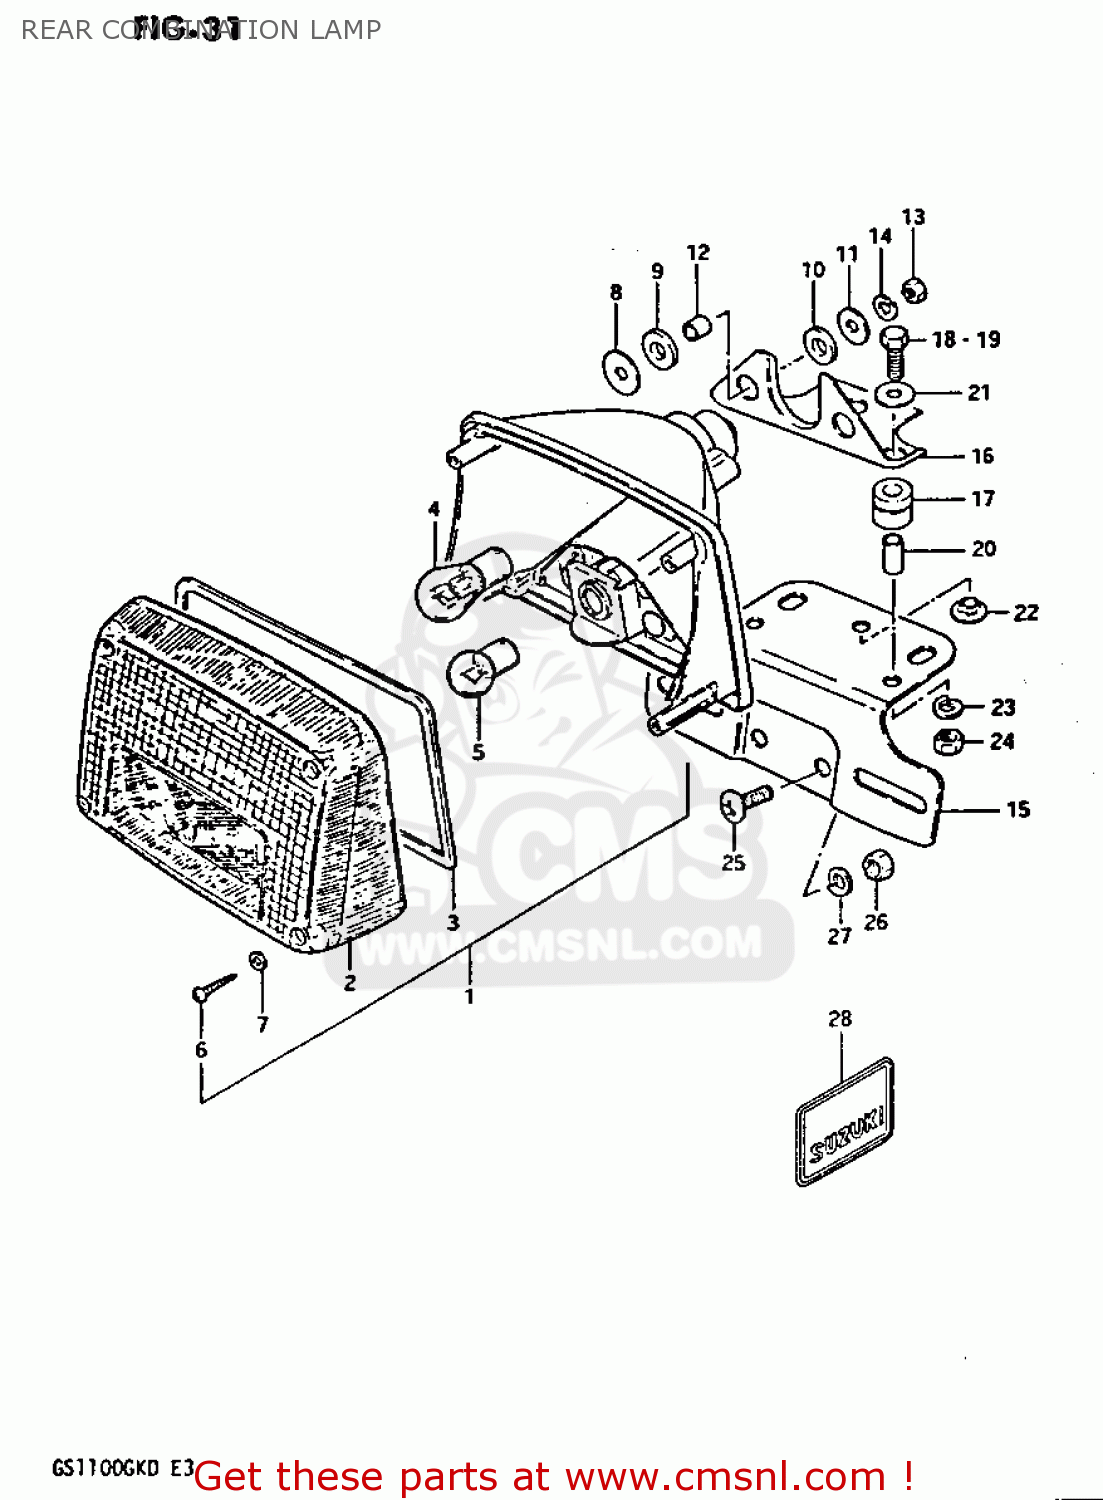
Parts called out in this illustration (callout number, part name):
1	LAMP ASSEMBLY,REAR COMBINATION
2	LENS
3	GASKET (NAS)
4	BULB(12V23W)
5	BULB(12V8W)
6	SCREW,REAR COMBINATION LAMP
7	GASKET (NAS)
8	WASHER
9	CUSHION
10	CUSHION
11	WASHER(6,5X22X1.6)
12	SPACER(6.1X9X7.5)
13	NUT
14	WASHER,LOCK
15	PLATE,REAR LICENSE
16	BRACKET,LICENSE PLATE
17	CUSHION, BRACKET
18	BOLT
19	BOLT
20	SPACER (6.4X9X15.5)
21	WASHER
22	WASHER
23	WASHER,LOCK
24	NUT
25	SCREW
26	NUT
27	WASHER,LOCK
28	EMBLEM,SEAT TAIL COVER
